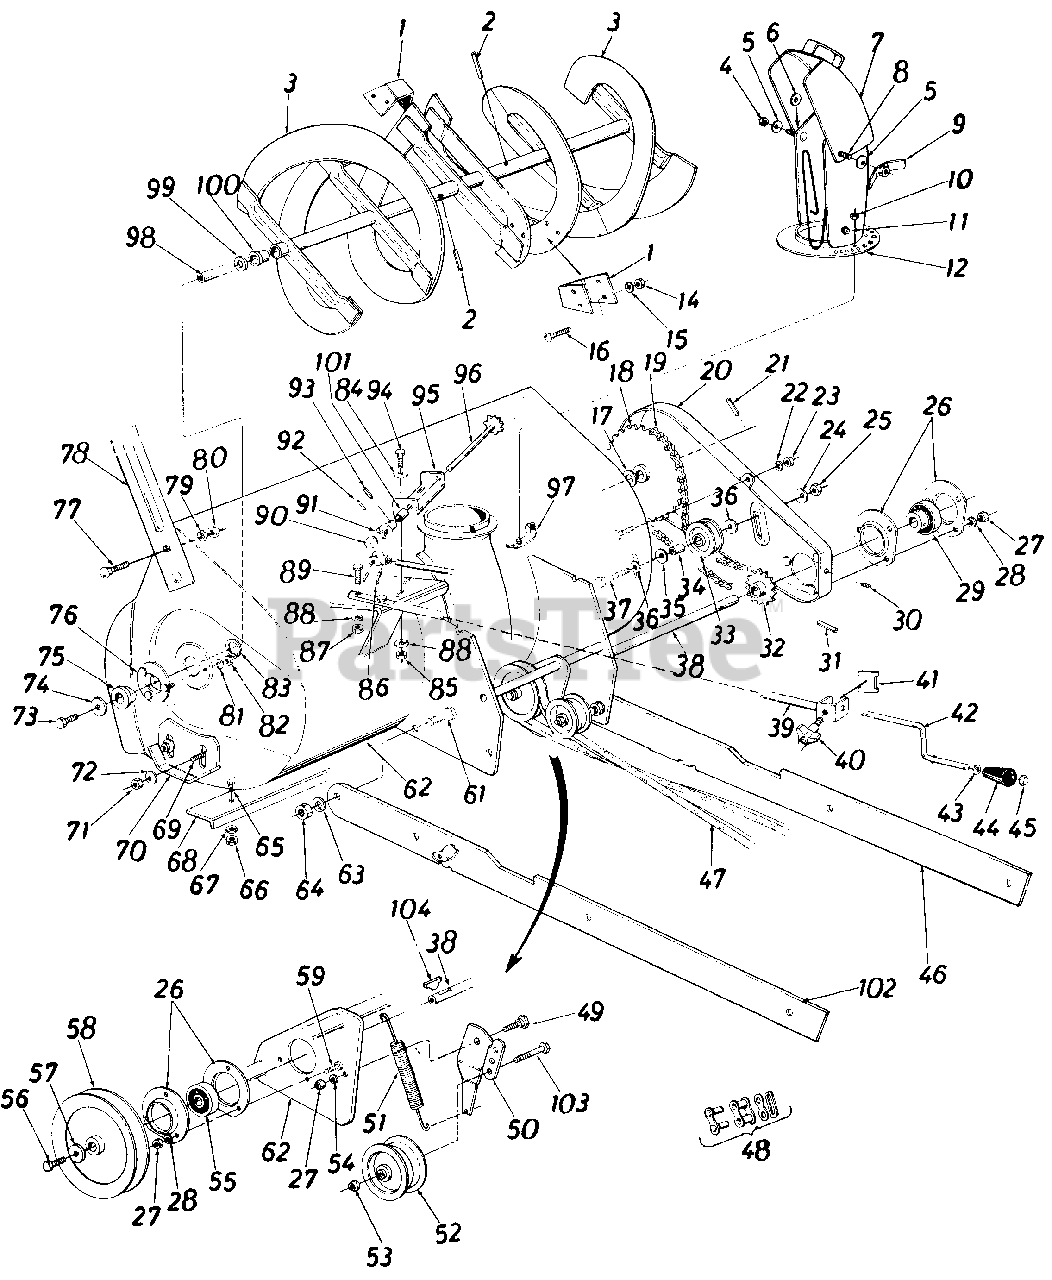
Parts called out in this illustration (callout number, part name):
1	Spiral Plate
2	Spring Pin Spir. 5/16 x 1.75" Lg.
3	Spiral Ass'y.
4	Hex Cent. L-Nut 5/16-18 Thd.
5	Bell. Wash.
6	Fl-Wash.
7	Top Chute Ass'y.
8	Car. Bolt 5/16-18 x .62" Lg.
9	Chute Wing Ass'y.
10	Hex Cent. L Nut 1/4-20 Thd.
11	Push Cap. 188" Dia. Rod
12	Chute Ass'y.
14	Hex Nut 5/16-18 Thd.*
15	L-Wash. 5/16" Scr.*
16	Car. Bolt 5/16-18x.62" Lg.*
17	Fl-Wash .
18	Sprocket Hub Ass'y. 40 Teeth
19	#420 Chain x 1/2" Pitch-77 Links
20	Chain Guard Ass'y.
21	Spring Pin Spir.-5/16
22	L-Wash. 5/16" Scr.*
23	Hex Nut 5/16-18 Thd.*
24	Bell. Wash.
25	Hex Ins. L-Nut 3/8-16 Thd.
26	Bearing Housing
27	Hex Nut 5/16-18 Thd.*
28	L-Wash. 5/16" Scr.*
29	Self Aligning Brg. w/Set Scr.
31	Spring Pin Spir.-5/16 x 1.75
32	14 Teeth Sprocket Ass'y.
33	1.875" Dia. Flat Idler
34	Idler Spacer
35	Fl-Wash.
36	Fl-Wash.
37	Hex Scr. 3/8-16x 2.00" Lg.*
38	Drive Shaft
39	Crank Support Tubing Ass'y.
40	Hand Knob 5/16-18 Thd.
41	Chute Crank Brkt.
42	Chute Crank
43	Fl-Wash.
44	Knob-Black 3/8" Dia. Hole
45	Push Nut 3/8" Rod
46	Linkage Arm Ass'y.
47	"V"-Belt 1/2" x 85" Lg. (Kevlar)
48	Master Link for #420 Chain
49	Shoulder Scr.
50	Idler Brkt. Ass'y.
51	Extension Spring
52	Fl. Idler with Flange
53	Hex Ins. Jam Nut 3/8-16 Thd.
54	L-Wash. 5/16" Scr.*
55	Self Aligning Brg.
56	Hex Nut 3/4-10 Thd.
57	Fl-Wash. 3/4" I.D.
58	5.50 O.D. x 5/8 Pulley
59	Hex Sems Scr. 5/16-18 x.75"
61	Hex Scr. 1/2-13 x 1.25" Lg.*
62	Spiral Housing Ass'y.
63	L-Wash. 1/2" Scr.*
64	Hex Nut 1/2-13 Thd.*
65	Car. Bolt 5/16-18 x .62" Lg.*
66	Hex Nut 5/16-18 Thd.*
67	L-Wash. 5/16" Scr.*
69	Car. Bolt 3/8-16 x.75" Lg.*
70	Slide Shoe
71	Hex Nut 3/8-16
72	Bell. Wash.
73	Hex Scr. 5/16-18 x.62" Lg.
74	Fl-Wash.
75	Flange Brg. with Flats
76	Brg. Housing Ass'y.
77	Car. Bolt 5/16-18 x .62" Lg.
78	Guide Blade
79	L-Wash. 5/16" Scr.*
80	Hex Nut 5/16-18 Thd.*
81	L-Wash. 5/16" Scr.*
82	Hex Nut 5/16-18 Thd.*
83	Snap Ring for 1.50" Dia. Shaft
84	Bell. Wash.
85	Hex Nut 5/16-18 Thd.*
86	Cotter Pin 3/32 x 1.00 " Lg. *
87	Hex Nut 5/16-18 Thd.*
88	L-Wash. 5/16" Scr.*
89	Hex Scr. 5/16-18 x 1.50" Lg.
90	Joint Block
91	Joint Brkt. Ass'y.
92	Spring Pin Roll 3/16" x .81" Lg. *
93	Spring Pin Roll 1/8x.75" Lg. *
94	Hex Scr. 5/16-18x.75" Lg.*
95	Chute Brkt.
96	Sprocket Shaft Ass'y.
97	Chute Flange Keeper Ass'y.
98	Spiral Axle
99	F l-Wash.
100	Plastic Bushing
101	Spacer .380 I.D. x.630 O.D. x .565
102	Linkage Arm Ass'y. R.H.
103	Hex Bolt 3/8-16 x 1.75" Lg.*
104	#61 Hi-Pro Key
